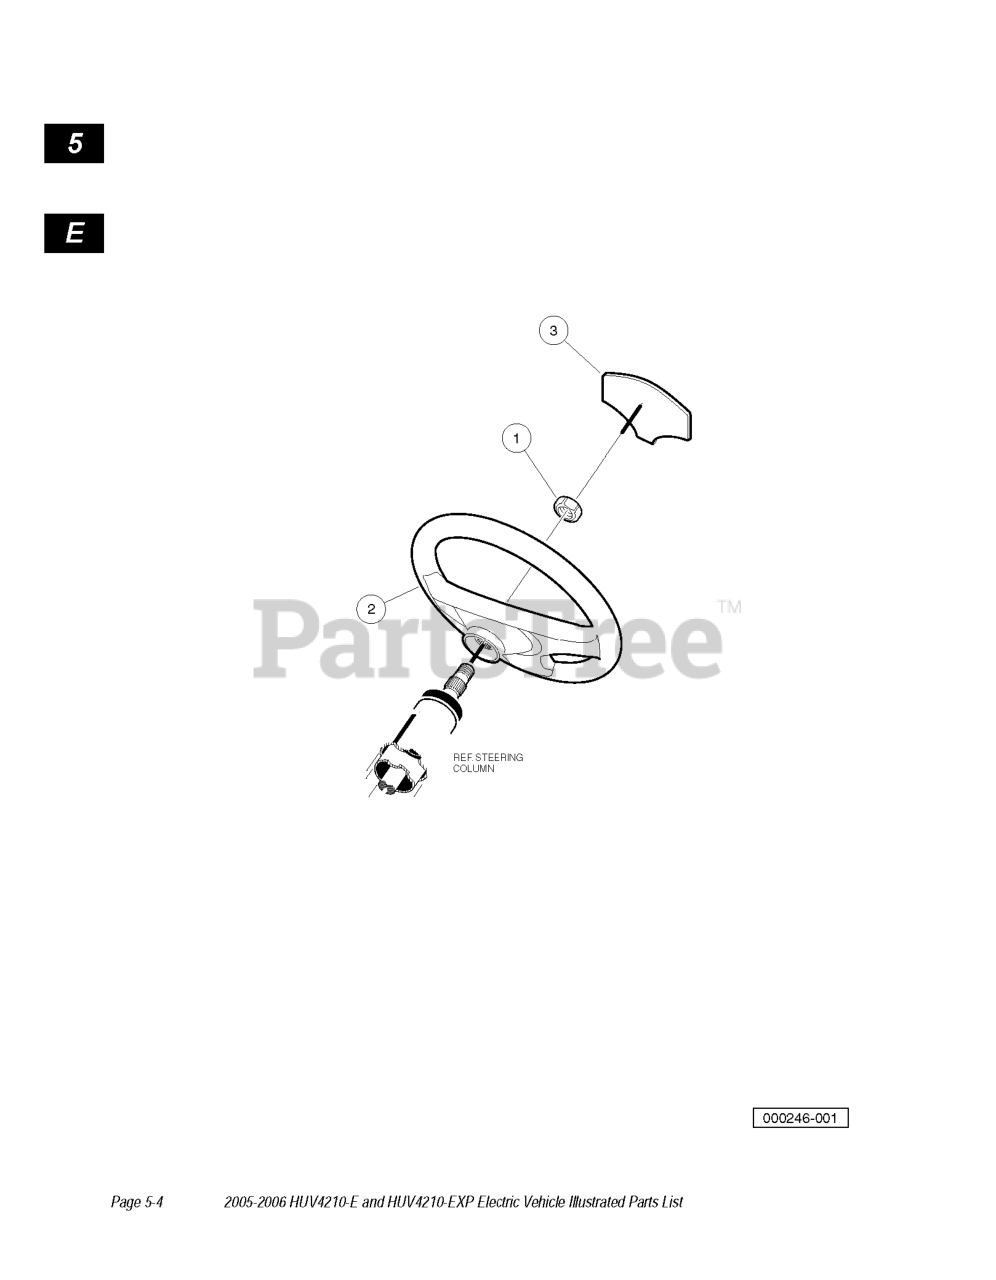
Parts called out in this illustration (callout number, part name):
1	NUT, 5/8-18 NYLON INSERT JAM
2	STEERING WHL, INTEGRA, SPLINE
3	WHEEL CENTER, INTEGRA
